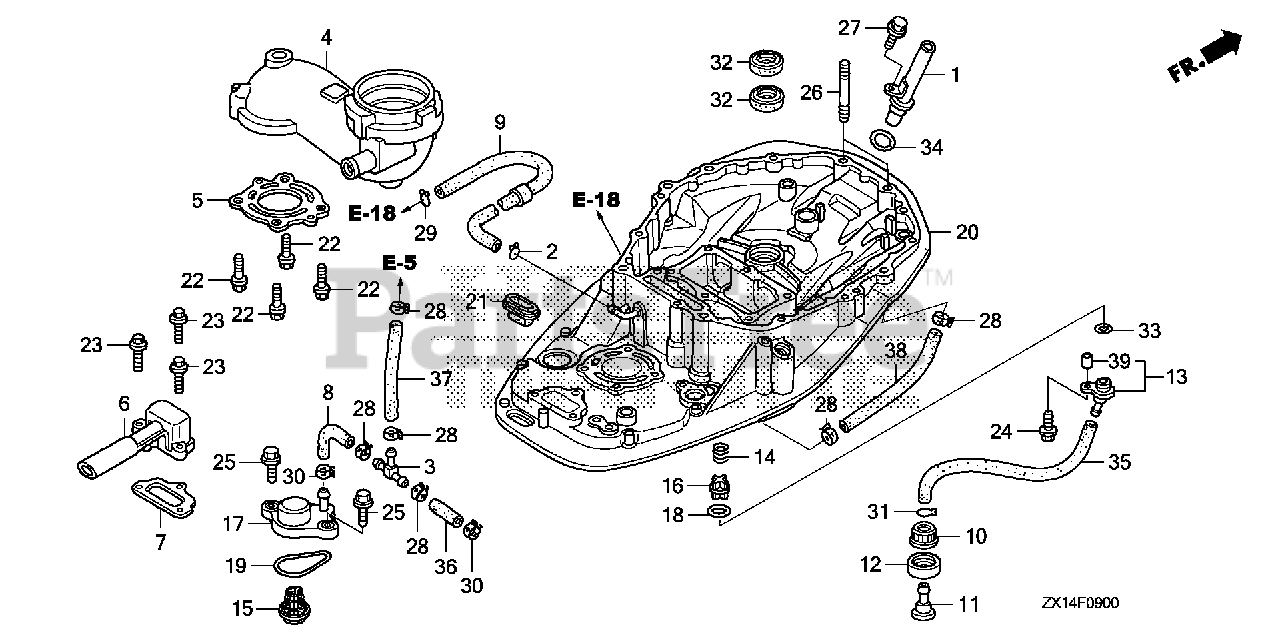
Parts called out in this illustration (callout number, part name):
1	PIPE, OIL LEVEL
2	CLIP, TUBE
4	GUIDE, EX. *NH8* (DARK GRAY)
5	GASKET, EX. GUIDE
6	PORT, IDLE EX.
7	GASKET, IDLE EX. PORT
8	TUBE, WATER RELIEF
9	TUBE F, WATER
10	NUT, WATER MOUTH
11	JOINT, WATER HOSE
12	SEAT, WATER MOUTH
13	COVER, FLUSH VALVE
14	SPRING, FLUSH VALVE
15	VALVE ASSY., RELIEF
16	VALVE, FLASH
17	COVER, RELIEF VALVE
18	GASKET, FLASH VALVE
19	O-RING, THERMOSTAT COVER
20	CASE, MOUNT *NH8* (DARK GRAY)
21	RUBBER, MOUNT CASE SEAL
22	BOLT, FLANGE (8X30)
23	BOLT, FLANGE (6X25)
24	BOLT, FLANGE (6X16) (ENGINE NO.)
24	BOLT, FLANGE (6X20) (ENGINE NO.)
25	BOLT, FLANGE (6X22)
26	BOLT, STUD (10X55)
27	BOLT, FLANGE (6X12)
28	CLAMP, TUBE (D10.5)
29	CLIP, TUBE (B12)
30	CLAMP, TUBE (D10.5)
31	CLIP B1, TUBE
32	SEAL, WATER (22X35X7)
33	O-RING (16MM)
34	O-RING (11.5X3.5)
35	BULK HOSE, FUEL (8X1000) (8X300)
36	BULK HOSE, VACUUM (7X3000) (7X40)
37	BULK HOSE, VACUUM (7X3000) (7X160)
38	BULK HOSE, VACUUM (7X3000) (7X200)
39	COLLAR, DISTANCE
